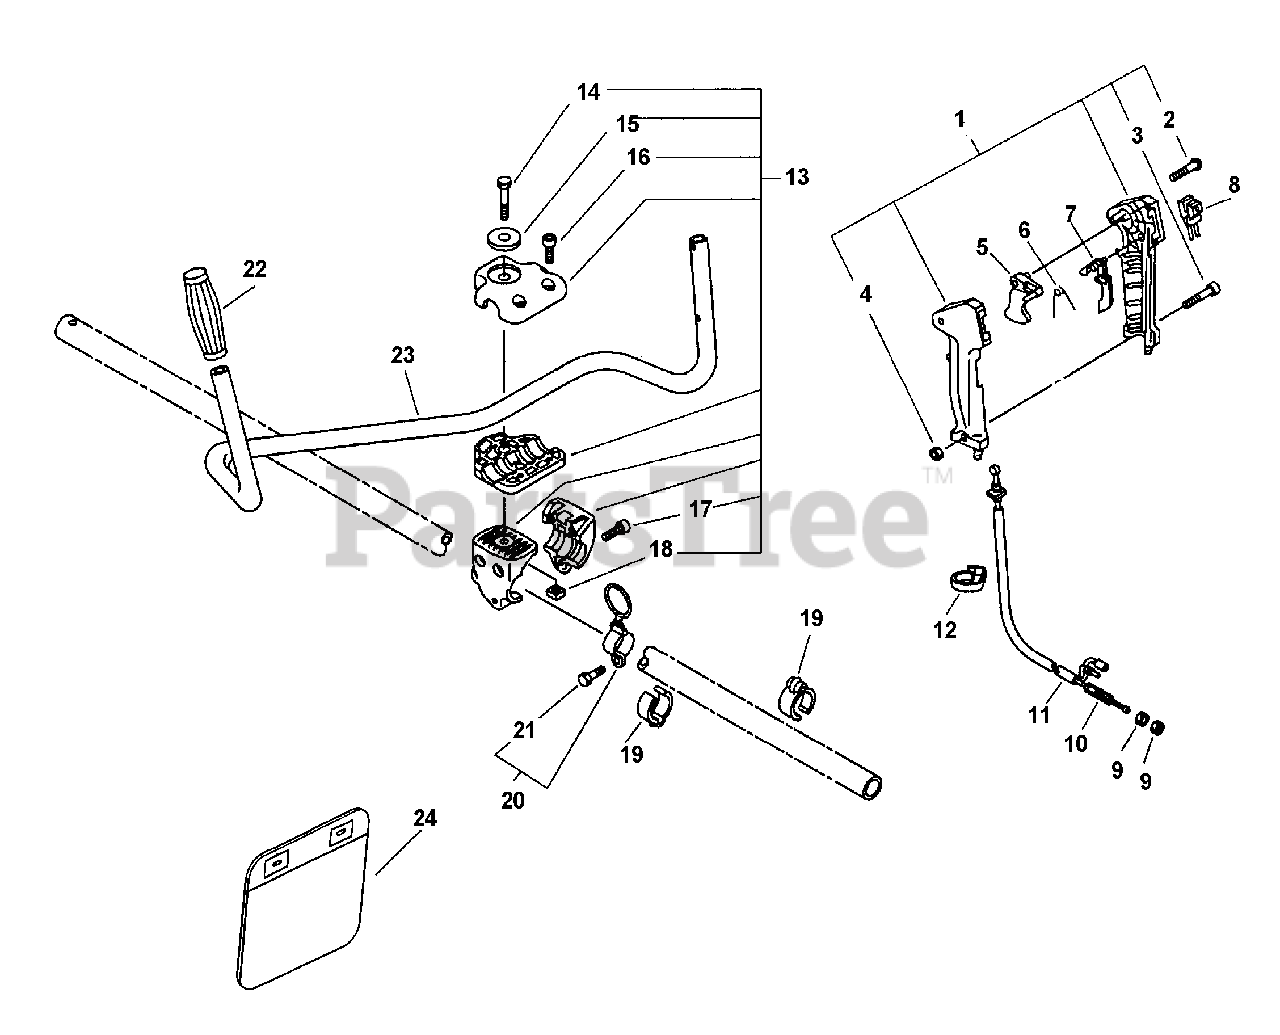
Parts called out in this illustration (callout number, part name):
1	THROTTLE CONTROL ASSY
2	SCREW - 3X25
3	SCREW - 5X30
5	TRIGGER, THROTTLE
6	SPRING, LOCKOUT LEVER
7	LOCKOUT, THROTTLE
8	IGNITION SWITCH ASSY
9	NUT - 6
10	CABLE, THROTTLE
11	TUBE, PROTECTIVE - CORRUGATED
13	HANDLE BRACKET KIT
14	BOLT - 8X55
15	WASHER - 8
16	SCREW - 5X20
17	SCREW - 5X30
20	HANGER KIT
21	BOLT - 5X12
22	GRIP, HANDLE - LEFT
23	HANDLE - FRONT
24	CUSHION
